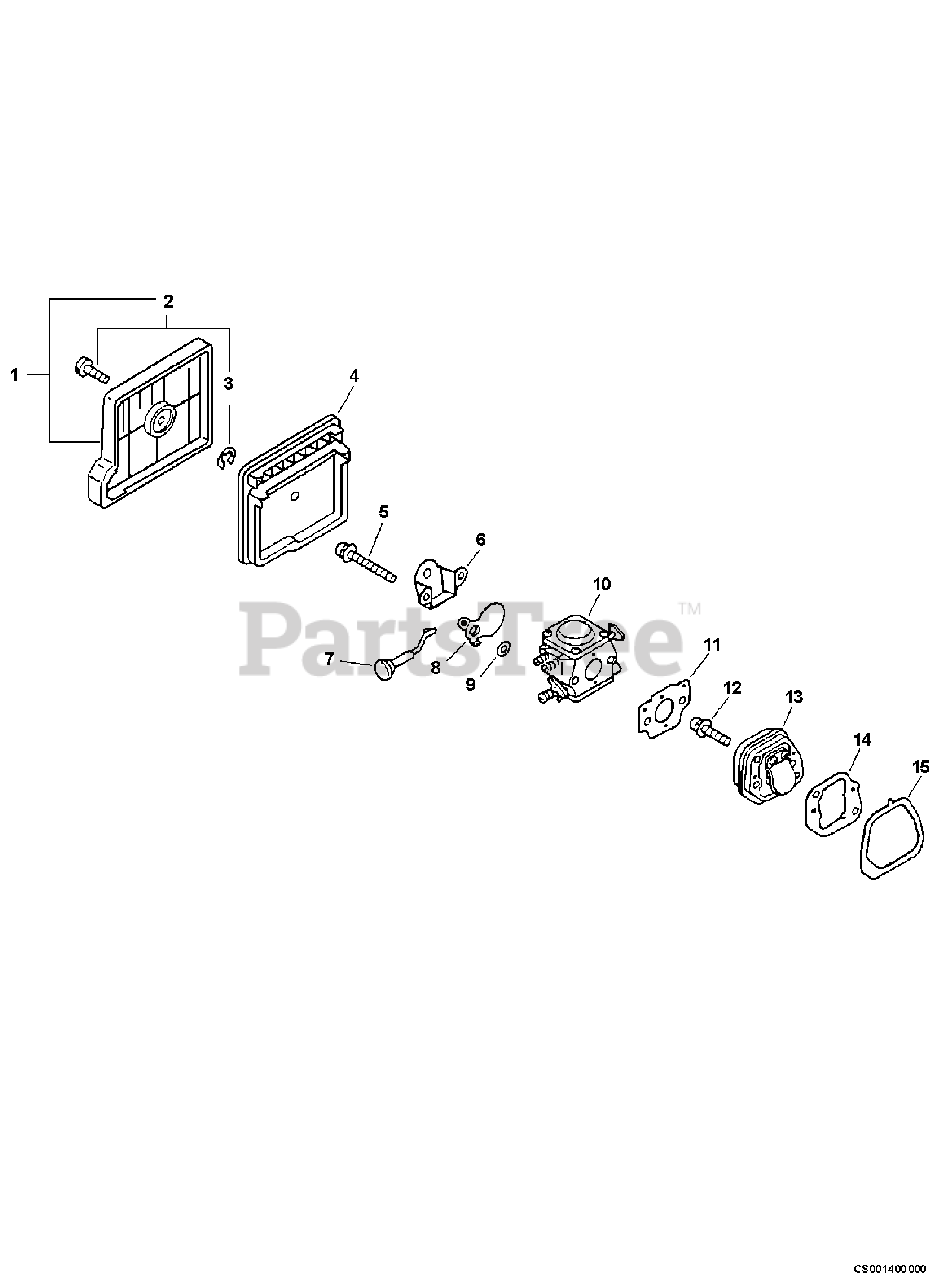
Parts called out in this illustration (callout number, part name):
1	AIR FILTER COVER ASSY
2	THUMBSCREW
3	RING, RETAINING - 4
4	FILTER, AIR
5	SCREW - 5X45
6	PLATE, PREVENT
7	ROD, CHOKE
8	SHUTTER, CHOKE
9	WASHER
10	CARBURETOR WT-589
11	GASKET, INTAKE
12	SCREW - 5X18
13	INSULATOR KIT
14	GASKET, INTAKE
15	SEAL
